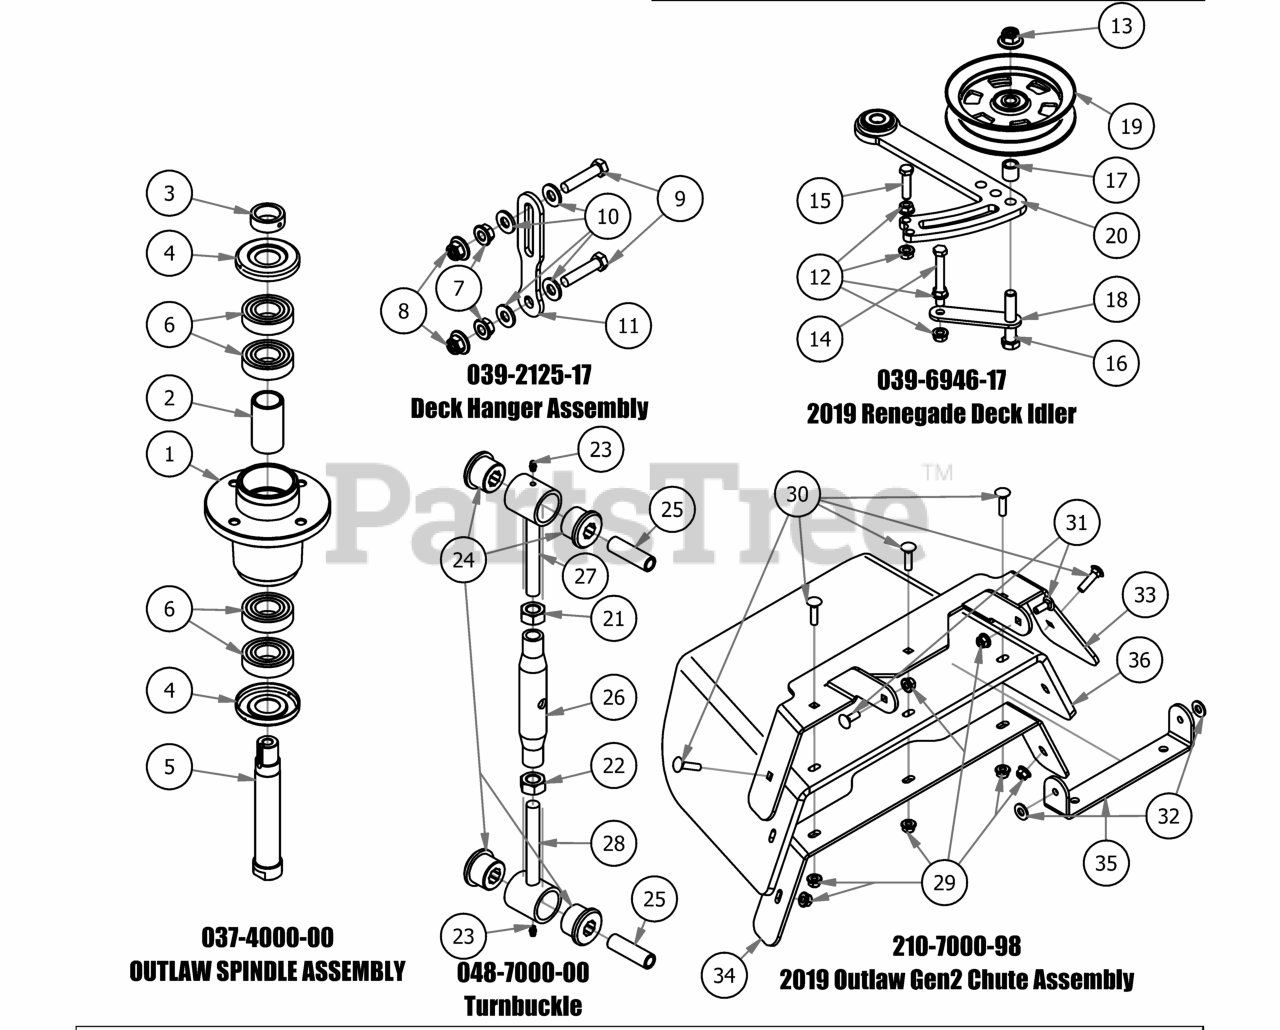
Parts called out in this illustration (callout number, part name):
1	4000 Series Spindle Housing
2	4000 Series Spindle Spacer
3	Locking Collar w/ 1/4"-20 Set Screw
4	Spindle Dust Cap
5	Spindle Shaft
6	Bearing - 6206
7	1/2" Flange Nut
8	1/2-13 NYLON INSERT FLANGE LOCKNUT ZINC
9	1/2-13X 2-1/4 GR Hex Bolts
10	.505 Nylon Spacer
11	Deck_Hanging_Tab
12	3/8" Flange Nut
13	1/2-13 NYLON INSERT FLANGE LOCKNUT ZINC
14	3/8-16x3 grade 5 hex bolt
15	3/8 x 1.5" Bolt
16	1/2" x 2 3/4" Hex Bolt
17	Spacer 3/4 OD x 1/2 ID x 3\4 Length
18	Belt Tensioner Retainer Plate
19	5" Idler Pully
20	2019 Deck Tensioner
21	Hex Nut, 11/16-12
22	Hex Nut, 11/16-12 Left Handed
23	1/4" Press in Grease Fitting
24	Polyeurethane Bushing
26	2015 Outlaw Toplink Body
27	Right-Handed End
28	2015 Outlaw Toplink LH End
29	5/16" Nylon Flange Nut
30	5/16" x 1 1/4" Carriage Bolt
31	5/16" x 7/8" Carriage Bolt
32	.360 ID Plastic Washer
33	2019 Upper Chute Bracket
34	2019 Lower Chute Bracket
35	2019 Chute Hanger
36	2019 Belted Chute with Logo
